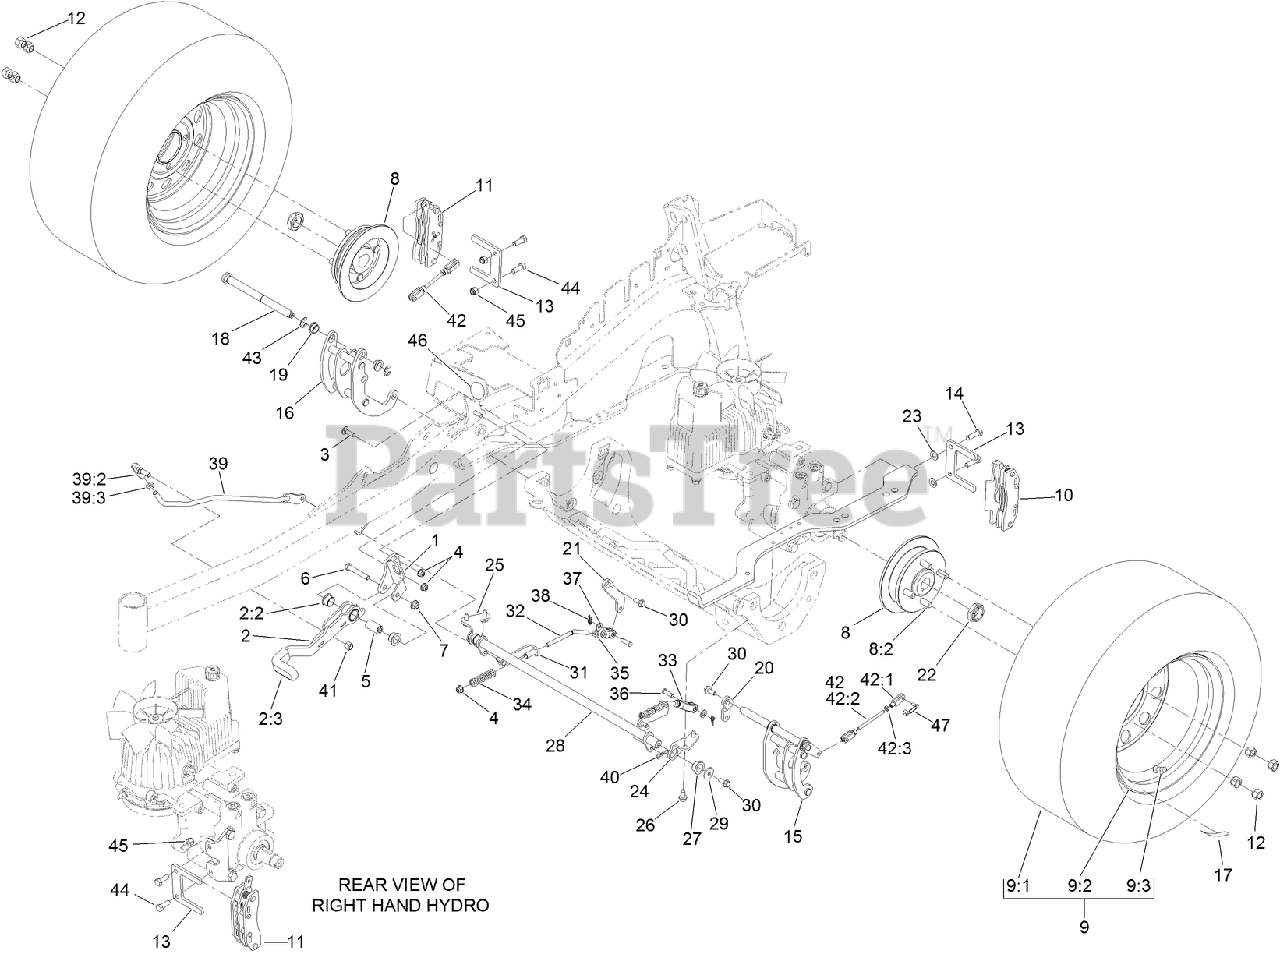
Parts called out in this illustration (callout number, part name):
1	BRACKET-MOUNT
2	BRAKE LEVER ASM
2:2	BUSHING-FLANGE
2:3	GRIP-LEVER
3	BOLT-CARR
4	NUT-HF, NI
5	HANDLE-PIVOT, BRAKE
6	SCREW-HH
7	NUT-HF, NI
8	WHEEL HUB ASM
8:2	STUD-WHEEL
9	WHEEL AND TIRE ASM
9:3	STEM-VALVE
10	CALIPER-BRAKE
11	CALIPER-BRAKE, RH
12	NUT-LUG
13	PLATE-MOUNT, BRAKE
14	SCREW-LOCK, PATCH
15	MOUNT-BELLCRANK, LH
16	MOUNT-BELLCRANK, RH
17	DECAL-TORQUE, WHEEL HUB LUG
18	BELLCRANK
19	BUSHING
20	ARM-INNER, LH
21	ARM-INNER, RH
22	LOCKNUT
23	WASHER-FLAT
24	MOUNT-PIVOT, LH
25	MOUNT-PIVOT, RH
26	SCREW-HWHTF
27	BUSHING-FLANGE
28	SHAFT-CROSS
29	WASHER-FLAT
30	SCREW
31	BRACKET-L
32	LINKAGE-MID
33	YOKE-OFFSET
34	SPRING-COMPRESSION
35	NUT-JAM
36	PIN-CLEVIS
37	WASHER-PLAIN
38	PIN-COTTER, LOCKING
39	FRONT LINKAGE ASM
39:2	END-TIE ROD, RH
39:3	NUT-HJ
40	PIN-COTTER, LOCKING
41	NUT-LOCK
42	REAR LINKAGE ASM
42:1	YOKE
42:2	LINKAGE, REAR
42:3	NUT-JAM
43	E-RING
44	SCREW-HH
45	NUT-LOCK, NI
46	SPACER
47	PIN-CLEVIS, SPRING
